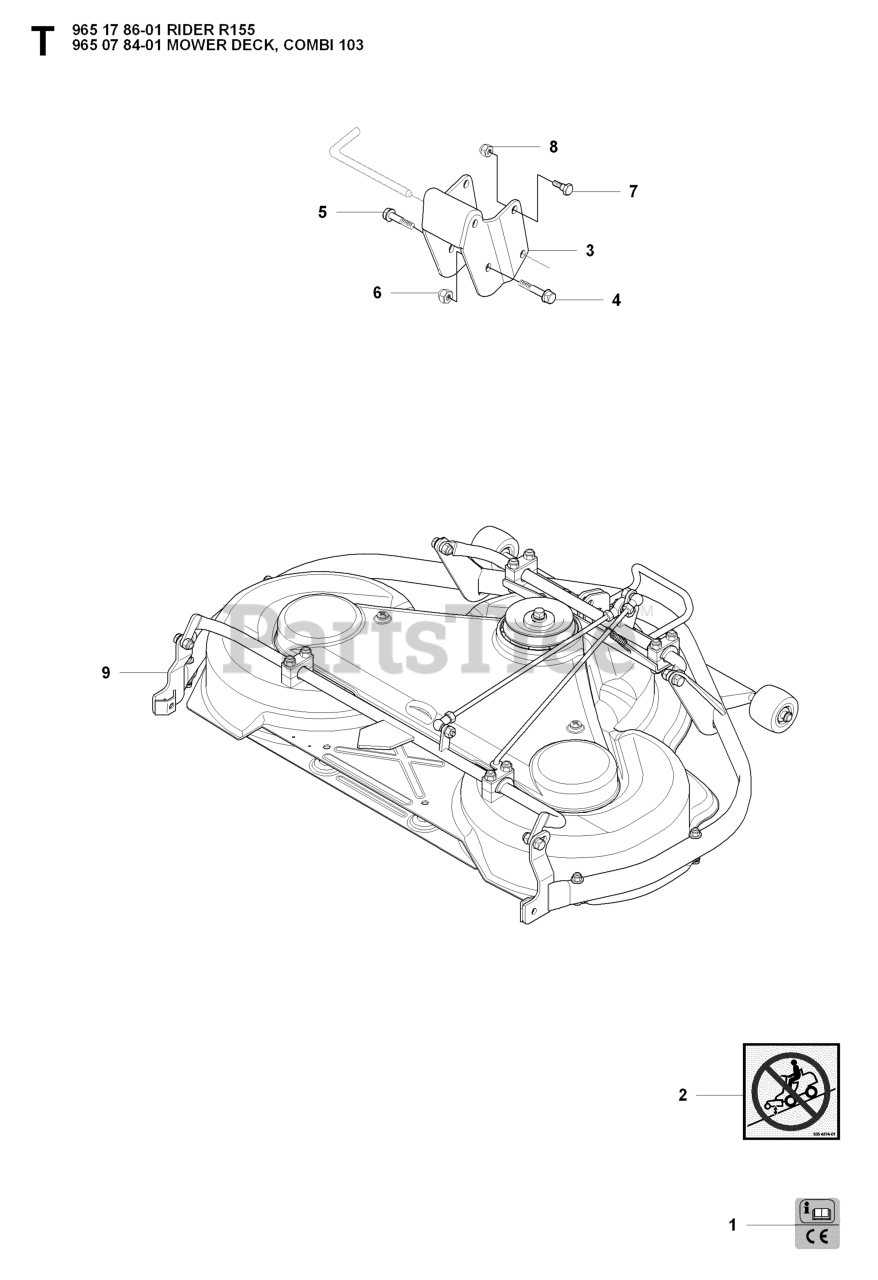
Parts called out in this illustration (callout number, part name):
5	Hex Head Capscrew, M12 X 1.75 X 30 DIN933ZP
8	LOCKNUT M8
9	DECK COMBI 103
